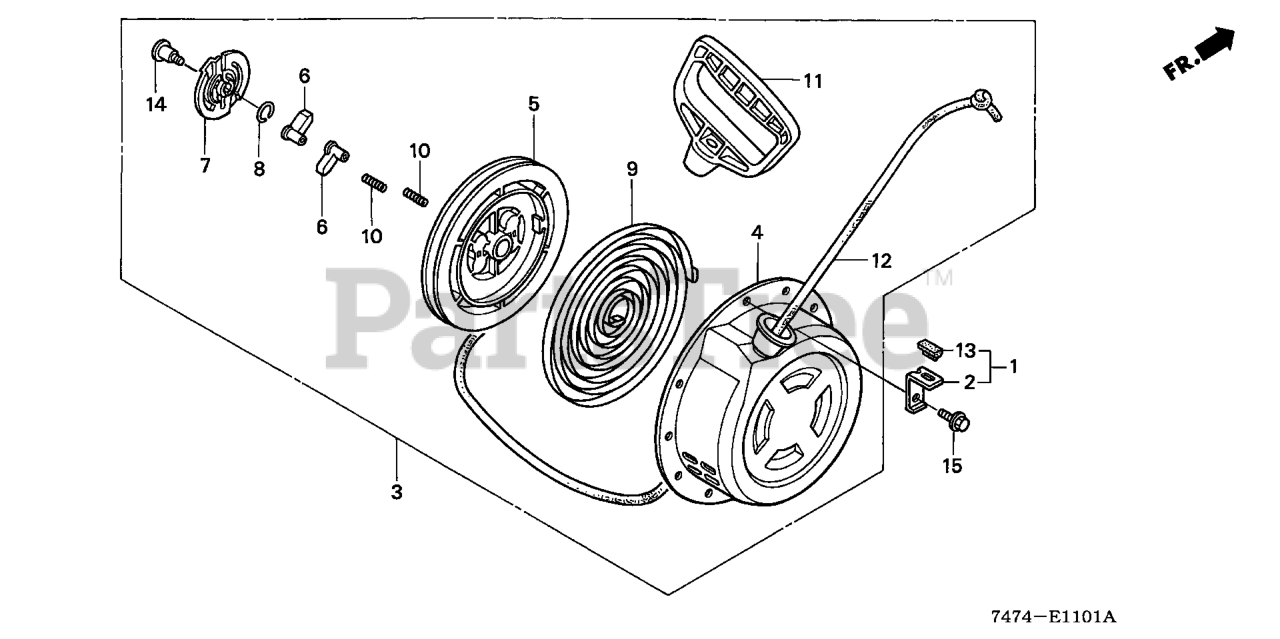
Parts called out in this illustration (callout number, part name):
1	STAY ASSY., FUEL TANK
2	STAY, FUEL TANK
3	STARTER, RECOIL
4	CASE, RECOIL STARTER
5	REEL, RECOIL STARTER
6	RATCHET, STARTER
7	GUIDE, RATCHET
8	SPRING, FRICTION (ENGINE NO.)
9	SPRING, RECOIL STARTER
10	SPRING, RETURN (ENGINE NO.)
11	GRIP, STARTER
12	ROPE, RECOIL STARTER (#5X73") (NA USE ALT:08550-ZG921-11)
13	STOPPER, DISCHARGE GUARD
14	SCREW, SETTING (ENGINE NO.)
15	BOLT, FLANGE (6X10)
